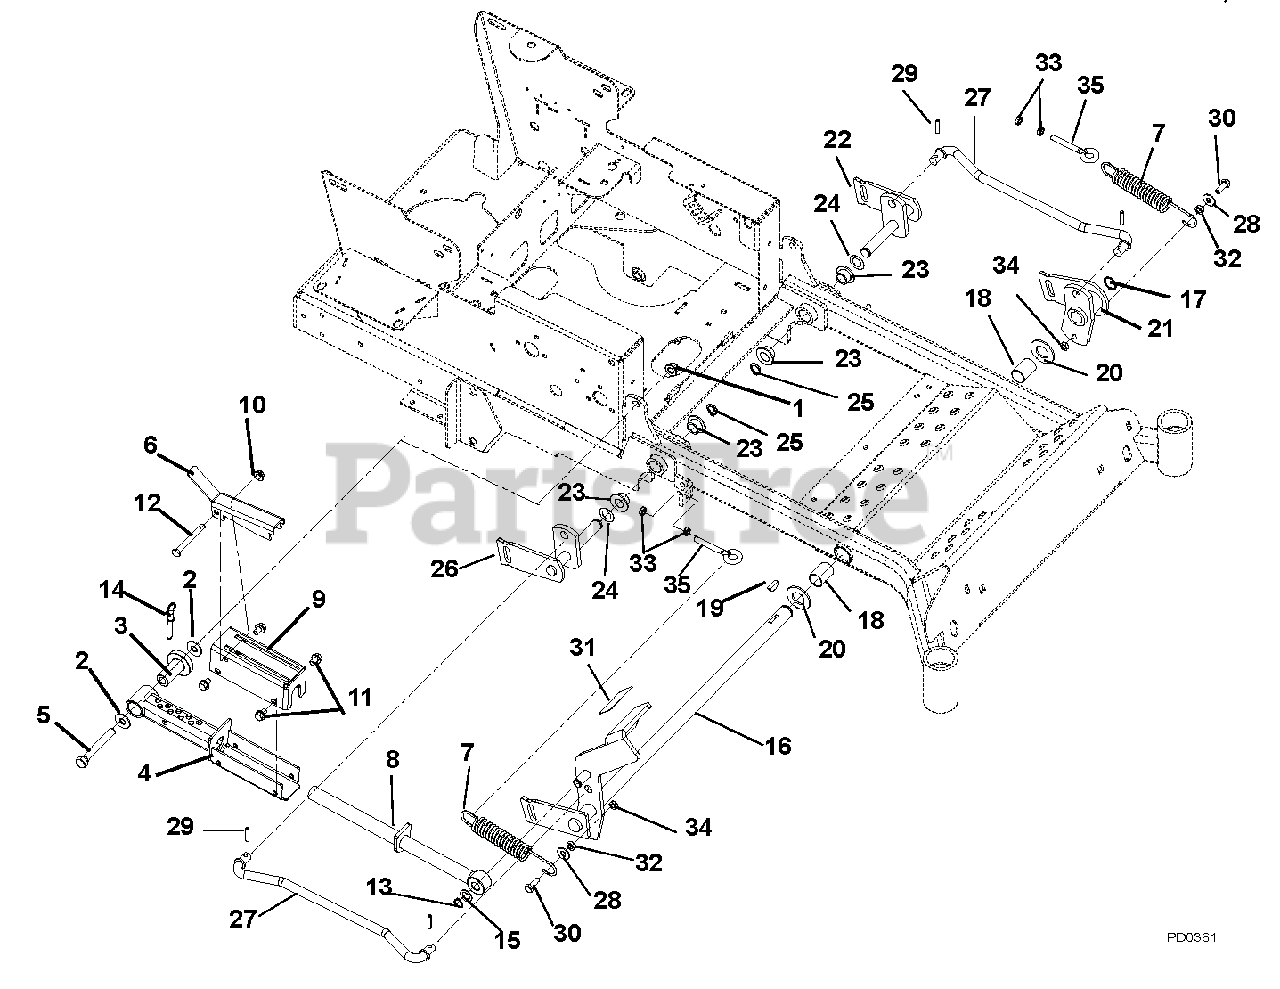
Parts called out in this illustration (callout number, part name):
1	@NUT-LK-NYL-FLG .50-13 YWZC
2	WSHR-FL-STL .531X1.250X.10 YWZ
3	BEARING, PEDESTAL
4	WMT, MECHANICAL LIFT
5	@BLT-HEX .50-13X3.75 GR5 YWZC
6	LOCK-UP, MECH LIFT
7	SG-TENS .162X1.25X8.25 WLD 25
8	WMT, MECH. LIFT SHAFT (.62)
9	WMT, MECH LIFT COVER
10	@NUT-LK-NYL-FLG .38-16 YWZC
11	@SCR-TAP .38-16X.50 HWH TR YWZ
12	@BLT-HEX .38-16X3.25 GR5 YWZC
13	RG-RTNG-EXT .625X.050
14	PIN, SPRING BALL .375OD X 1.50
15	WSHR-FL-STL .630X1.005X.062 YZ
16	WMT, FOOT OPERATED DECK LIFT
17	RG-RTNG-EXT 1.00X.078
18	BSHG,1.00ID X 1.125OD X 1.50LG
19	KEY-WDRF .25X1.00 HRD #15
20	WSHR-FL-STL- 1.062X2.0X.134 YZ
21	WMT, LH FRONT MOWER LIFT
22	WMT, LH REAR LIFT ARM (100)
23	BSHG-FLG .762X1.0X.580X1.48 NY
24	WSHR-HDND-THRST .758X1.23X.031
25	RG-RTNG-EXT .689X.078
26	WMT, RH REAR LIFT ARM (100)
27	ROD, LIFT ASSIST 16.35"
28	@WSHR-FL-STL.438X1.00X.083 YWZ
29	PIN-ROLL .250X1.25 STNLESS STL
30	@BLT-HEX .38-16X1.00 GR5 YWZC
31	GRIP, PEDAL 1.50 X 3.00
32	BSHG-SLV .377X.624X.235
33	NUT-HEX-JAM .375-16 YWZC
34	@NUT-LK-CTR-JAM .375-16 YWZC
35	BLT-EYE .375-16X2.50 YWZC
